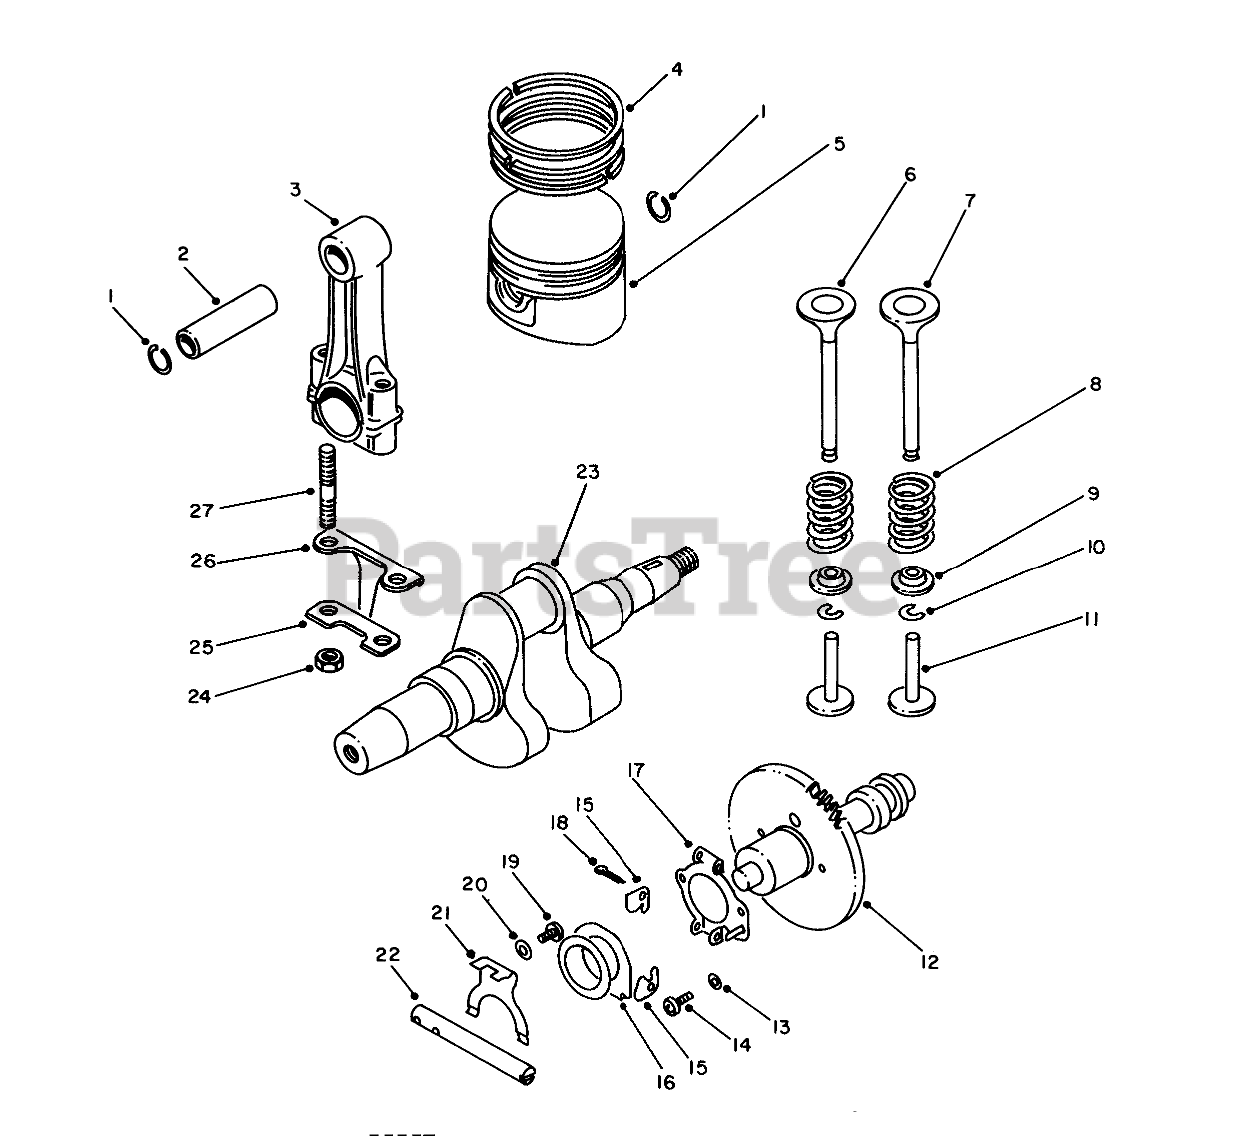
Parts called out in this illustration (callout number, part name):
1	Snap Ring
2	Pin-Piston
3	Connecting Rod Assembly (Incl. Ref. #24-27)
4	Ring Set
5	Piston
6	Valve-Exhaust
7	Valve-Intake
8	Spring-Valve
9	Retainer
10	Cotter
11	Tappet (L:48.3)
12	Cam Shaft
13	Lockwasher
14	Screw
16	Spacer
17	Bracket
18	Cotter Pin
19	Screw
20	Washer
21	Plate-Shift
22	Shaft-Throttle Return
23	Crankshaft
25	LOCK PLATE
26	Plate-Splasher
